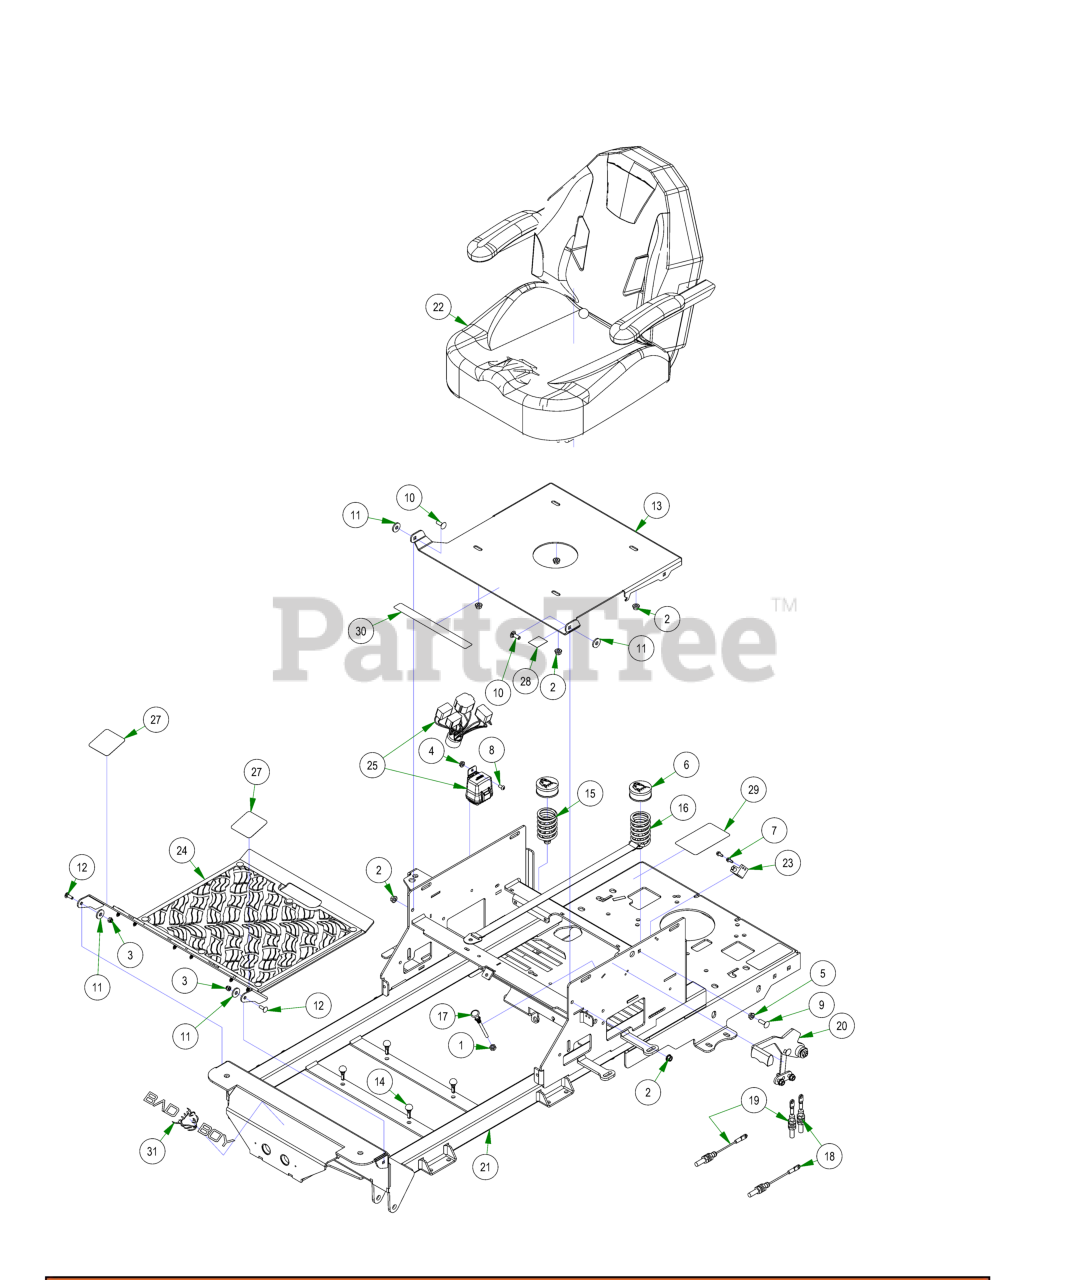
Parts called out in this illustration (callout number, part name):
1	3/8-24 HEX NUT ZINC YELLOW
2	5/16-18 NYLON INSERT FLANGE LOCKNUT ZINC
3	1/4-20 NYLON INSERT LOCKNUT ZINC
4	1/4-20 HEX SERRATED FLANGE NUT HARD/ZINC
5	5/16-18 HEX SERRATED FLANGE NUT HARD/ZINC
6	Spring Cap Cover
7	12-24 X 1/2 HEX WASHER UNLSOT F TCS ZINC
8	1/4-20 X 1/2 BUTTON SOCKET CAP SCREW 18-8 STAINLESS STEEL
9	5/16-18 X 1 CARRIAGE BOLT (GR.8) ZINC
10	5/16-18 X 7/8 CARRIAGE BOLT ZINC
11	.360 ID X .983 OD X .120 THICK FLAT WASHER NYLON
12	1/4-20 X 3/4 CARRIAGE BOLT (GR.5) ZINC
13	Seat Plate 2016
14	2023 Floor Board Rubber Bumper
15	Seat Spring Assembly
16	2022 Mav/HD seat spring assembly with strap
18	2021 Load Balanced Brake Cable 1
19	2021 Load Balanced Brake Cable 2
20	2021 Load Balanced Brake Handle Assembly
21	2024 ZT Elite Frame
22	2021 ZT Elite Seat
23	Safety Switch
24	2021 Maverick Floorboard Assembly
25	2024 Wiring Harness with Clips
26	2024 EPA Build Date Punch Decal
27	2018 Maverick/2021 ZT Anti-Skid Steering Control Decals
28	2018 MZ/Magnum/ZT/MAV/Comp Out Brake Decal
29	Pump Belt Route Decal-Pump Plate
30	Outlaw Warning Decal
31	Flying Bulldog Front Bumper Decal
